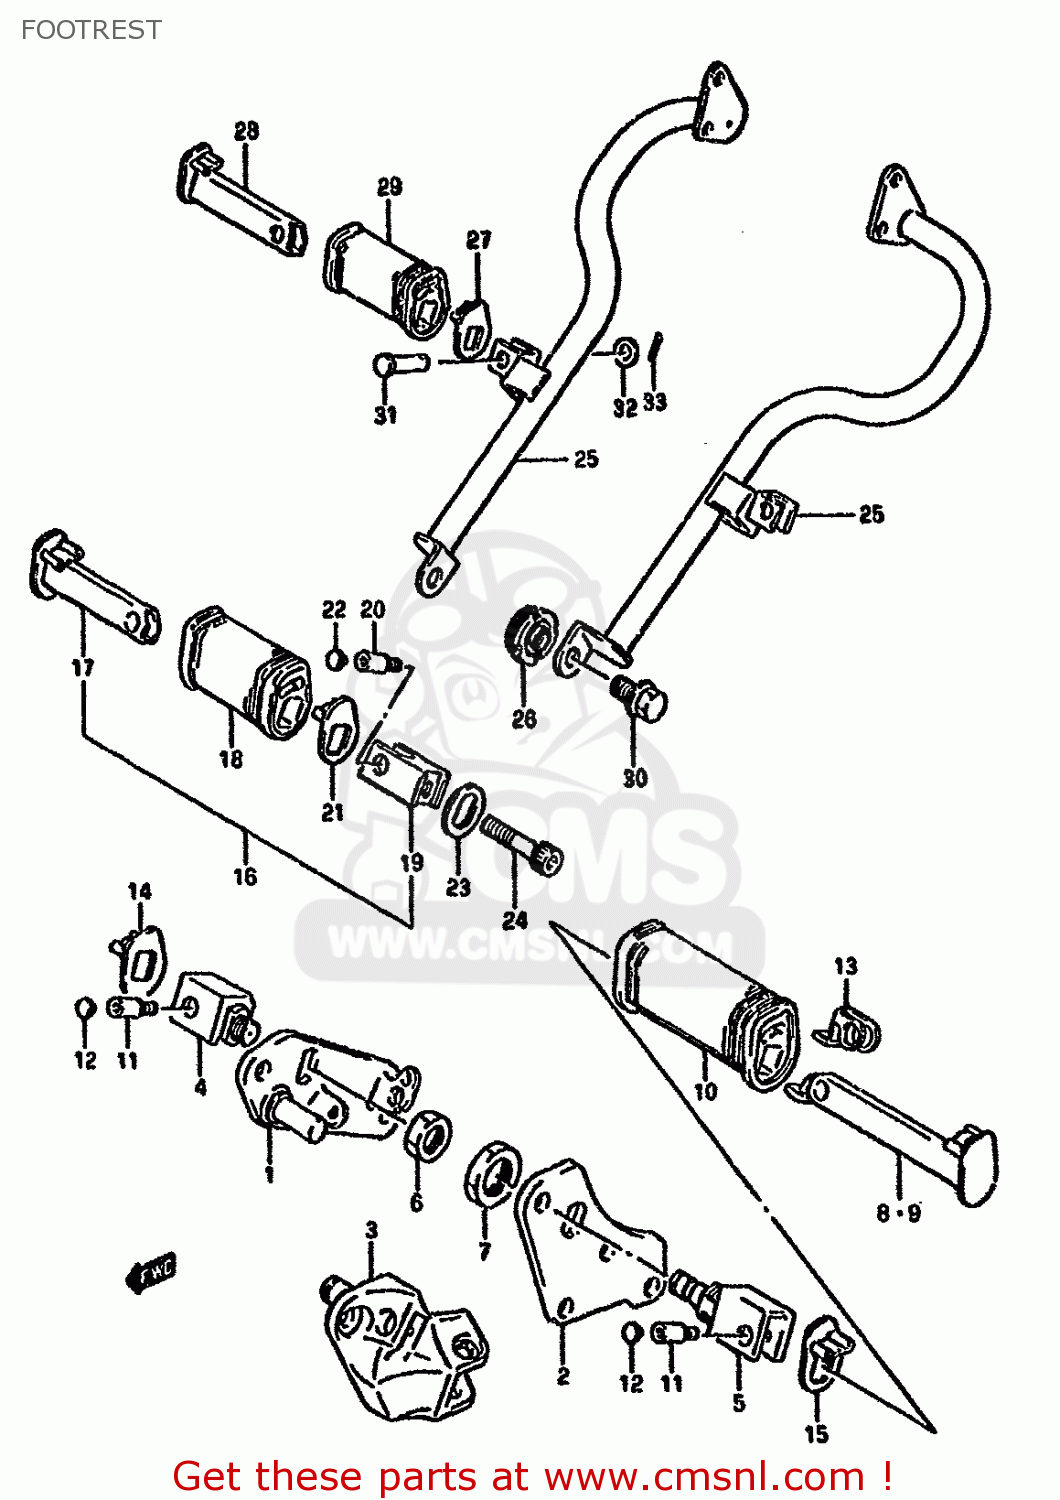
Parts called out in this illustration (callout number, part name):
1	BRACKET,FR FOOTREST,R
2	BRACKET,FRONT FOOTREST
3	BRACKET,FRONT FOOTREST
4	HOLDER,FR FOOTREST,R
5	HOLDER,FR FOOTREST,L
6	NUT
7	NUT
8	BAR,FRONT FOOTREST RH
9	BAR,FRONT FOOTREST LH
10	RUBBER,FR FOOTREST
11	BOLT,FRONT FOOTREST RUBBER
12	CAP,PILLION FOOTREST BOLT
13	CUSHION,FR FOOTREST
14	WASHER,FR FOOTREST,R
15	WASHER,FR FOOTREST,L
16	FOOTREST ASSY,PILLION,R
17	BAR COMP,PILLION FOOTREST
18	RUBBER,PILLION FOOTREST
19	BAR,PILLION FOOTREST
20	BOLT,FRONT FOOTREST RUBBER
21	WASHER,FR FOOTREST,R
22	CAP,PILLION FOOTREST BOLT
23	WASHER,PILLION FOOTREST HOLDER
24	BOLT
25	HOLDER,PILLION FOOTREST RH
26	BOSS,PILLION FOOTREST
27	WASHER,FR FOOTREST,R
28	BAR COMP,PILLION FOOTREST
29	RUBBER,PILLION FOOTREST
30	BOLT
31	PIN
32	WASHER 10MM
33	PIN 25X20
